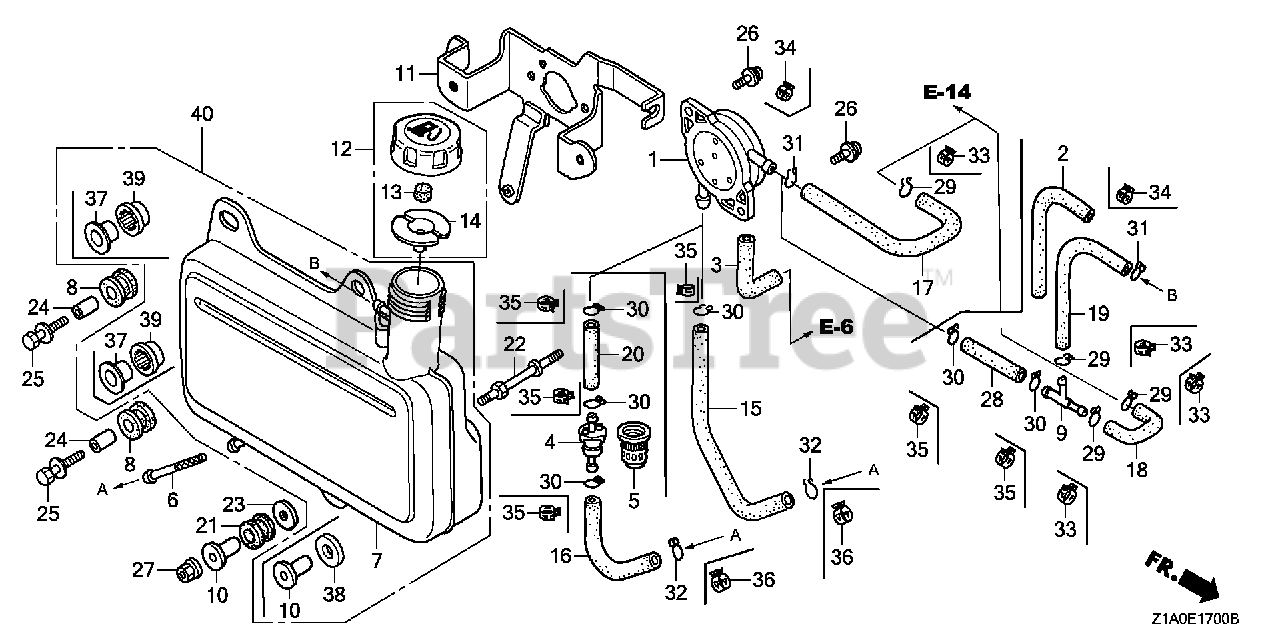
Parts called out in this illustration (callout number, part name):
1	PUMP ASSY., FUEL
3	TUBE, DIAPHRAGM
6	FILTER, FUEL
7	TANK KIT, FUEL
7	TANK, FUEL
8	RUBBER B, TANK MOUNTING
10	COLLAR, FUEL TANK SETTING
11	STAY A, FUEL TANK
12	CAP ASSY., FUEL TANK
13	SPONGE, FUEL CAP BREATHER
14	GASKET, FUEL CAP
15	TUBE, FUEL TANK
17	TUBE, FUEL
21	CUSHION, RR. FENDER
22	BOLT, FUEL TANK STUD (H=30MM)
23	WASHER (6MM)
24	COLLAR (14X6.1)
25	BOLT-WASHER (6X25)
26	SCREW-WASHER (5X14)
27	NUT, FLANGE (6MM)
29	CLIP, TUBE (B8)
30	CLIP, TUBE (B10)
31	CLIP, TUBE (C9)
32	CLIP, TUBE (C11)
33	CLIP, TUBE (D8)
34	CLIP, TUBE (D8.5)
35	CLAMP, TUBE (D10)
36	CLAMP, TUBE (D12)
